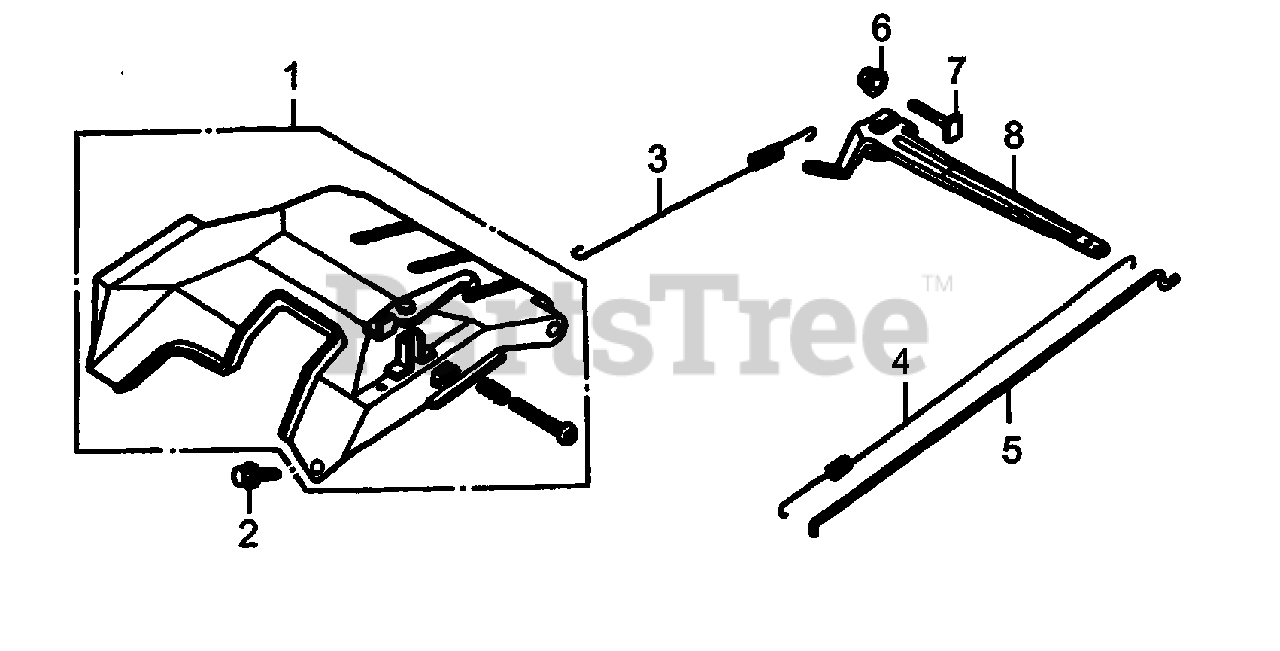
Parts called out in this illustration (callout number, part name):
1	CONTORL ASSY.
2	BOLT, FLANGE, 6X12
3	SPRING, GOVERNOR A
4	SPRING, GOVERNOR B
5	ROD, GOVERNOR
6	NUT, FLANGE, M6
7	BOLT, GOVERNOR ARM
8	ARM, GOVERNOR
